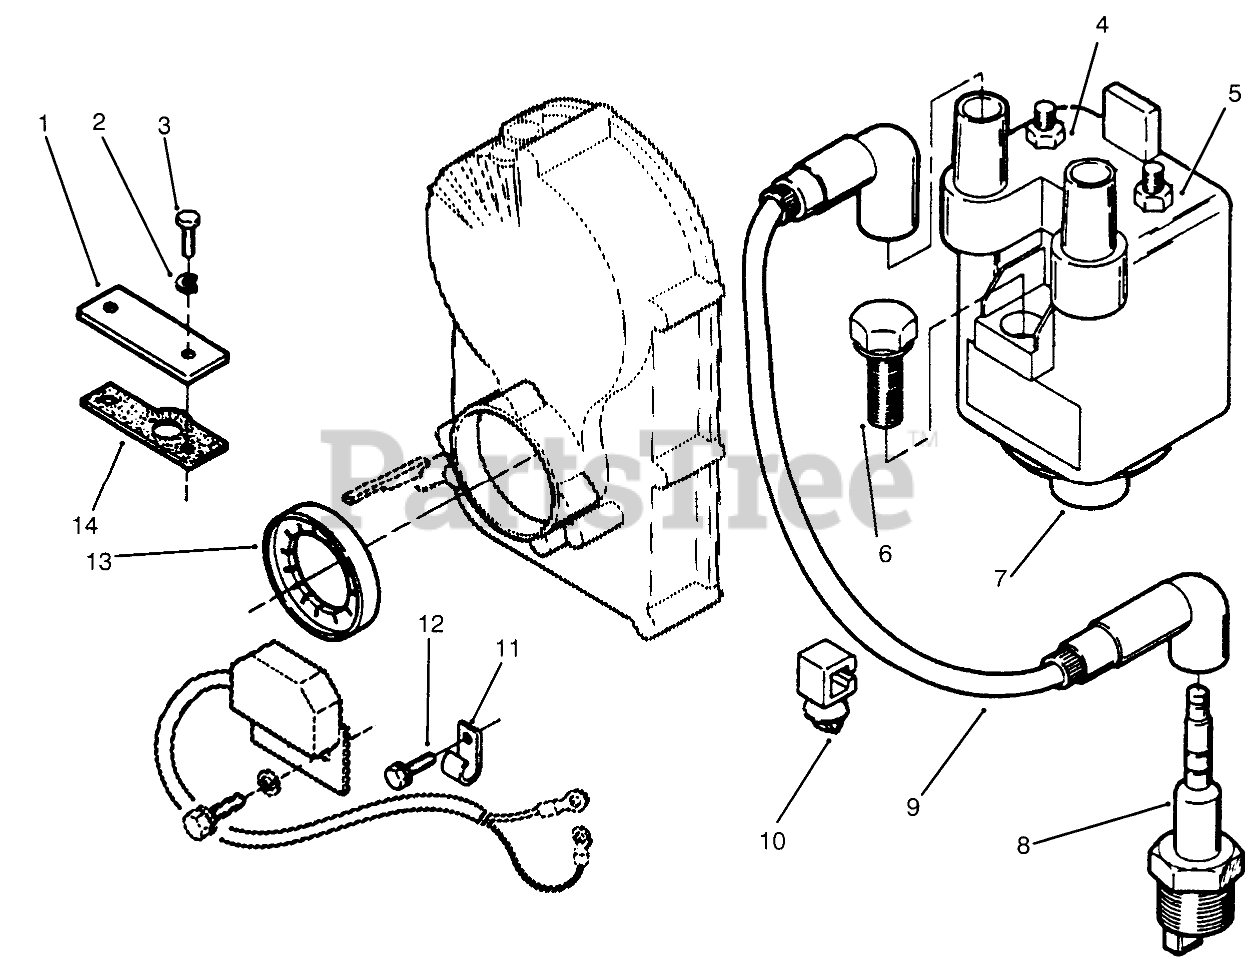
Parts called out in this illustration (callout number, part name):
1	PLATE-COVER
2	WASHER-FLAT
3	SCREW - CAP HEX HEAD
4	NUT-HEX FLANGE
5	NUT-HEX FLANGE
6	HEX-HEAD CAP SCREW
7	Coil-Battery Ignition (Incl. Ref. #4-5)
8	SPARK PLUG
9	Wire-Plug
10	WIRE ROUTING CLIP
11	CLIP-WIRE
12	SCREW-HH
13	ROTOR-IGNITION
14	Gasket-Plate
